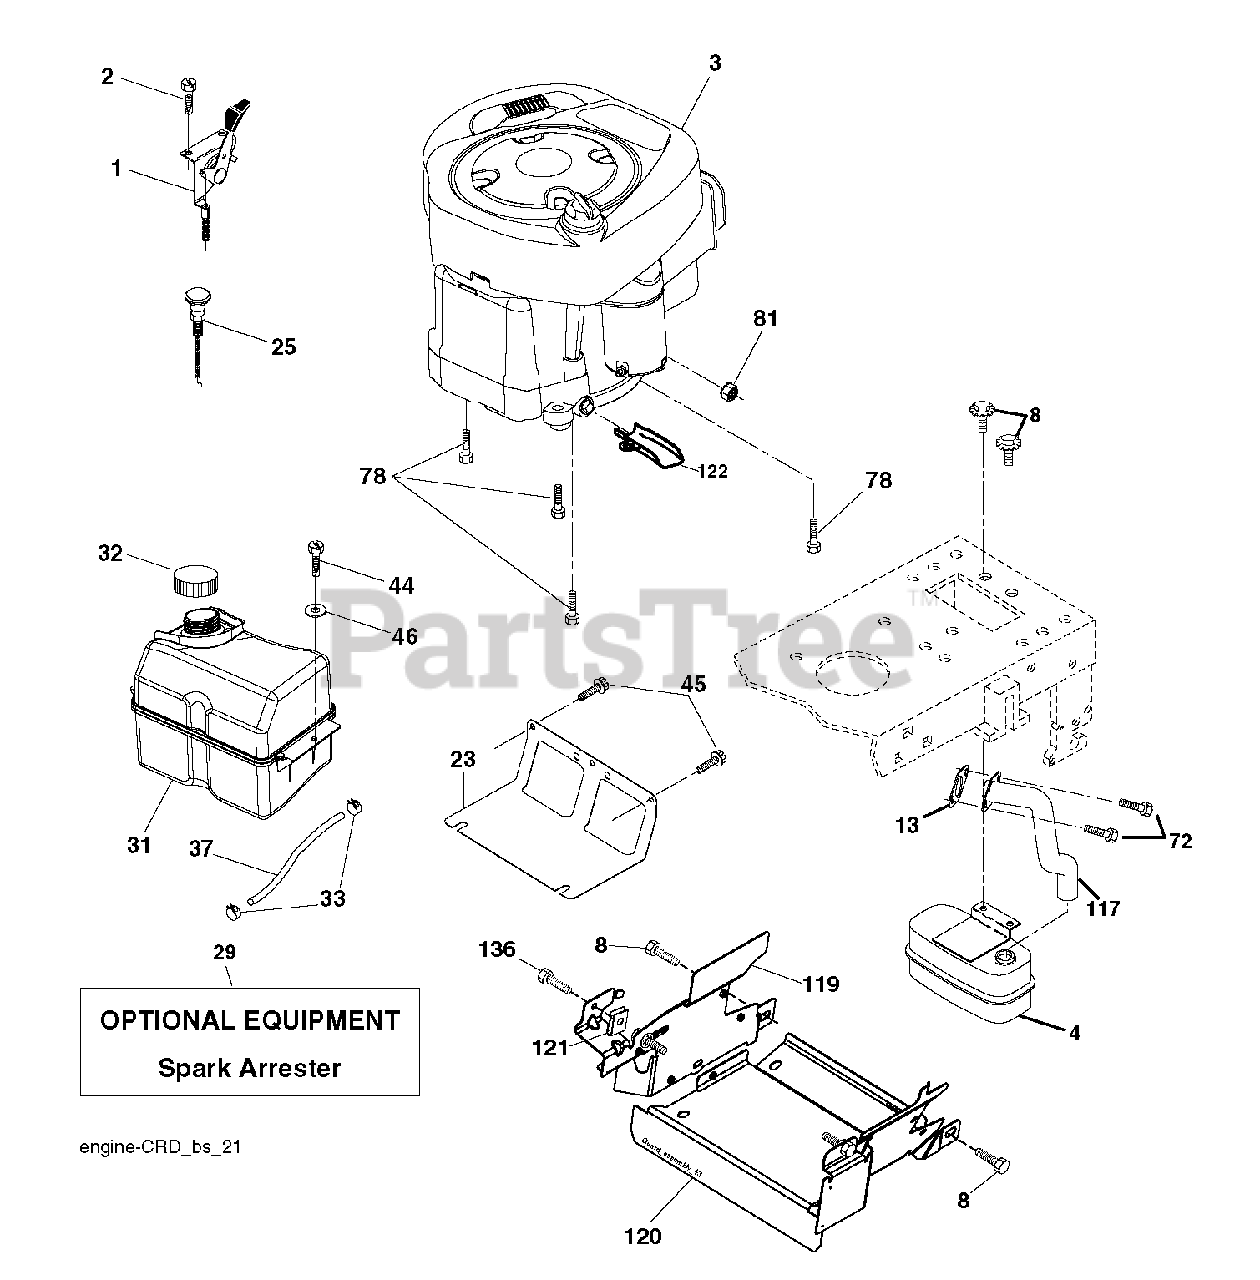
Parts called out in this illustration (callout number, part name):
1	CONTROL TH/CH FLAG
2	SCREW
4	MUFFLER.SINGLE.CYL.KOHL/B&S
8	BOLT, 5/16-18 X 1 3/4
13	REPL BY 532 27 22-93
23	SHEILD.BROWNING.DBR.GUARD
29	ARRESTER SPARK (OPTIONAL)
31	TANK.ASM.FRNT.2.GA.DAPCO.E10
32	CAP ASM.FUEL.2.25"FR.
33	HOSE CLAMP
37	LINE.FUEL.20
44	SCREW HEXWSHR 1/4-20X3/4
45	SCREW, 3/8-16X3/4
72	SCREW.SOCKET HD.5/16-1
78	SCREW.3/8-16
81	NUT
117	EXHAUST.TUBE.B&S.
122	EXTENSION DRAIN OIL
136	SCREW.1/4-20X5/8
